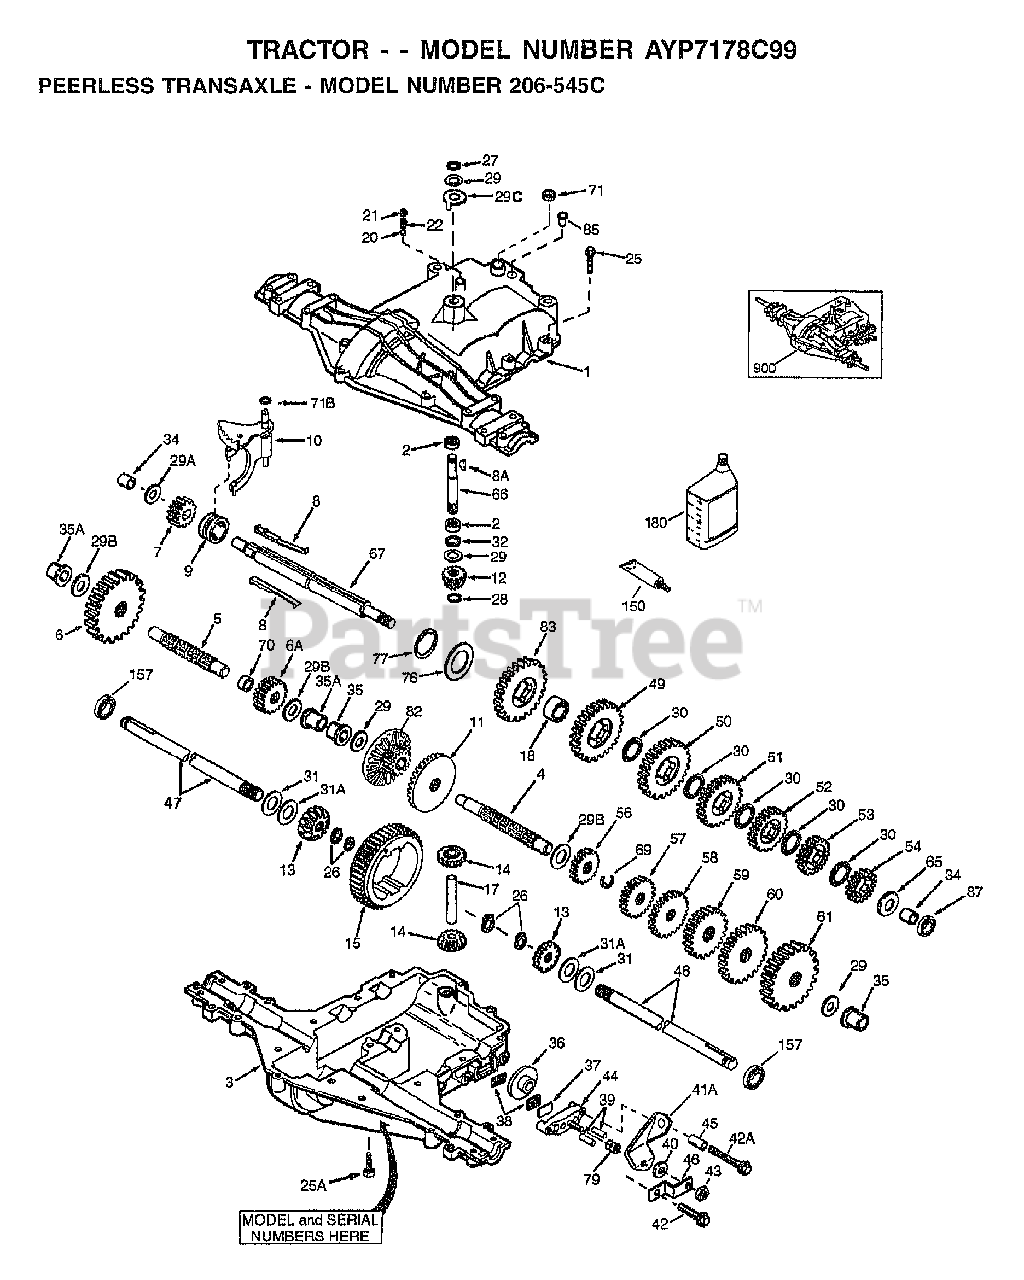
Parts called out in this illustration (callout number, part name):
1	TRANSAXLE COVER
2	NEEDLE BEARING 5/8" ID
3	TRANSAXLE CASE
4	COUNTERSHAFT
5	OUTPUT SHAFT
6	SPUR GEAR (38 TEETH)
6A	SPUR GEAR (15 TEETH)
7	SPUR GEAR (11 TEETH)
8A	KEY, WOODRUFF
9	COLLAR, SHIFTER
10	SHIFT ROD & FORK
11	BEVEL GEAR (30 TEETH)
12	INPUT BEVEL PINION (13TEETH)
13	BEVEL GEAR (13 TEETH)
14	BEVEL GEAR (13 TEETH)
15	RING GEAR (43 TEETH)
18	SPACER, NEUTRAL
21	SCREW, 3/8-16 X 3/8"
25A	SCREW 1/4-20 X 1-3/8"
26	RING RETAINER
27	RING, RETAINER
28	RETAINING RING
29	WASHER THRUST
29B	WASHER THRUST
29C	P/N CONFLICT - CHECK WITH SUPPLIER
30	WASHER THRUST
31A	FLAT WASHER
32	OIL SEAL 5/8"
34	BUSHING 9/16"
35	FLANGED BUSHING 5/8" ID
35A	FLANGED BUSHING 3/4"
37	PLATE BRAKE PAD
41A	BRAKE LEVER
42A	SCREW, 1/4-20 X 2-1/4
43	LOCKNUT 5/16-24
44	HOLDER BRAKE PAD
46	BRKT BRAKE LEVER
49	SPUR GEAR (29 TEETH)
50	SPUR GEAR (27 TEETH)
51	SPUR GEAR (23 TEETH)
52	SPUR GEAR (19 TEETH)
53	SPUR GEAR (16 TEETH)
54	SPUR GEAR (15 TEETH)
56	SPUR GEAR (11 TEETH)
57	SPUR GEAR (13 TEETH)
58	SPUR GEAR (17 TEETH)
59	SPUR GEAR (21 TEETH)
60	SPUR GEAR (24 TEETH)
61	SPUR GEAR (25 TEETH)
66	INPUT SHAFT
67	SHIFTER & BRAKE SHAFT
69	RETAINING RING
70	SPACER .890
71	SEAL SQUARE CUT
76	WASHER, THRUST
77	INVERTED RETAINING RING
82	BEVEL & SPUR GEAR (30 & 13 TEETH)
83	SPUR GEAR (27 TEETH)
85	OIL FILL PLUG
150	LIQUID GASKET RTV SILICONE
180	GEAR OIL 80W90
900	REPLACEMENT TRANSAXLE
